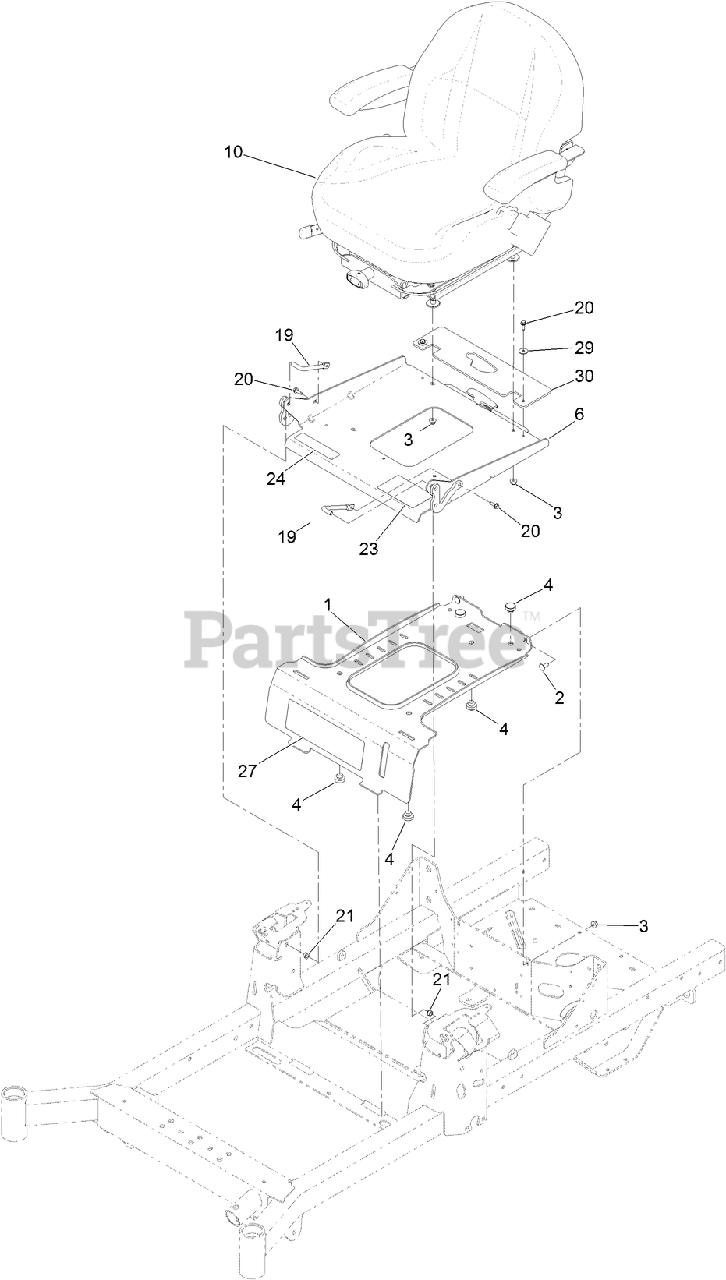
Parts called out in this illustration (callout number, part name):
1	PLATE-RETAINER, TANK
2	SCREW-CARR
3	NUT-HF, NI
4	BUMPER-RUBBER
6	SEAT PAN AND LATCH ASM
10	SEAT ASM
19	PIN-PIVOT, SEAT
20	SCREW-HWH, THREAD ROLL
21	BUSHING-FLANGED
23	DECAL-AID, SERVICE
24	DECAL-LATCH, SEAT
29	WASHER
30	GUARD-RUBBER
